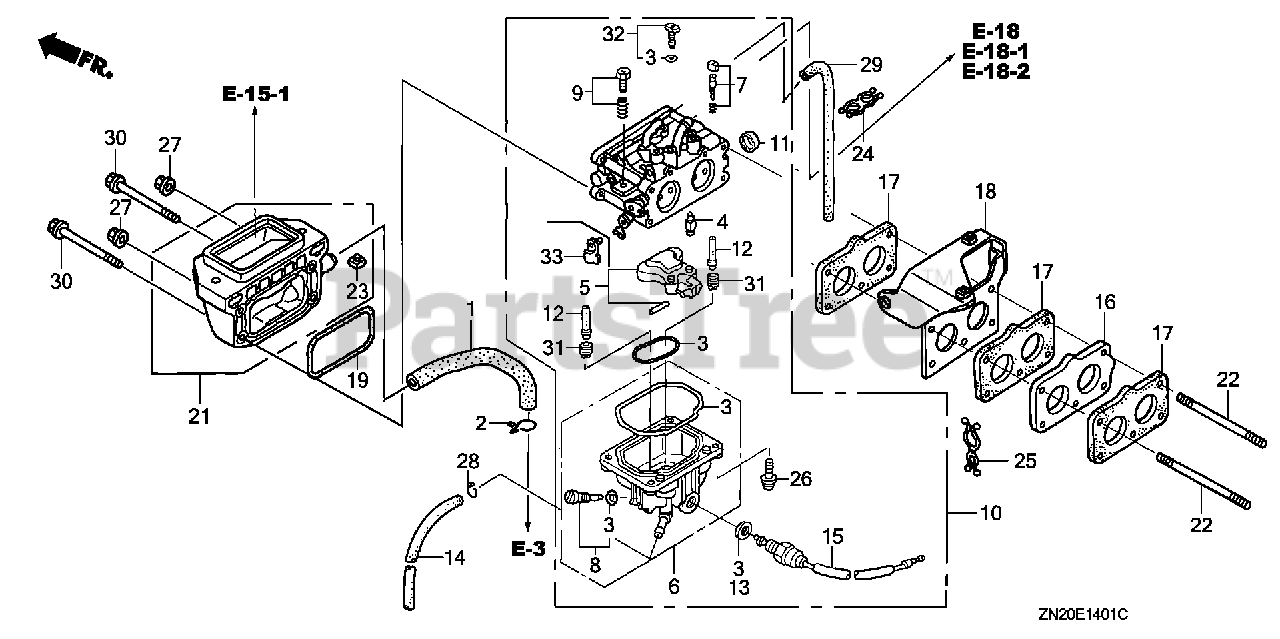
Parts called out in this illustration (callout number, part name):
1	TUBE, BREATHER
2	CLIP, BREATHER TUBE
3	GASKET SET (ADVENTURE GREEN) (CARBURETOR NO.)
4	VALVE SET, FLOAT (ADVENTURE GREEN) (CARBURETOR NO.)
5	FLOAT SET (ADVENTURE GREEN) (CARBURETOR NO.)
6	CHAMBER SET, FLOAT (ADVENTURE GREEN) (CARBURETOR NO.)
7	SCREW SET, PILOT (ADVENTURE GREEN) (CARBURETOR NO.)
8	SCREW SET, DRAIN (ADVENTURE GREEN) (CARBURETOR NO.)
9	SCREW SET, THROTTLE (ADVENTURE GREEN) (CARBURETOR NO.)
10	CARBURETOR ASSY. (BK02C A)
11	CAP, CHOKE DUST (ADVENTURE GREEN) (CARBURETOR NO.)
12	NOZZLE, MAIN (ADVENTURE GREEN) (CARBURETOR NO.)
13	WASHER, PLAIN (ADVENTURE GREEN) (CARBURETOR NO.)
14	TUBE, DRAIN
15	VALVE ASSY., SOLENOID (KEIHIN) (ADVENTURE GREEN) (CARBURETOR NO.)
16	INSULATOR, CARBURETOR
17	GASKET, CARBURETOR
18	STAY, FUEL PUMP
19	GASKET, AIR CLEANER
21	ELBOW, AIR CLEANER
22	BOLT, STUD (6X113)
23	NUT, INSERT (6MM)
24	CLIP, WIRE HARNESS
25	CLIP, PURSE LOCK
26	SCREW, PAN (4X12)
27	NUT, FLANGE (6MM)
28	CLIP, TUBE (B8)
29	BULK HOSE, VACUUM (4.5X1000) (4.5X540)
30	BOLT, FLANGE (6X115)
31	JET, MAIN (#90)
31	JET, MAIN (#92)
31	JET, MAIN (#95)
32	JET SET, PILOT (#40) (ADVENTURE GREEN) (CARBURETOR NO.)
33	ARM, THROTTLE LINKAGE (CARBURETOR NO.)
